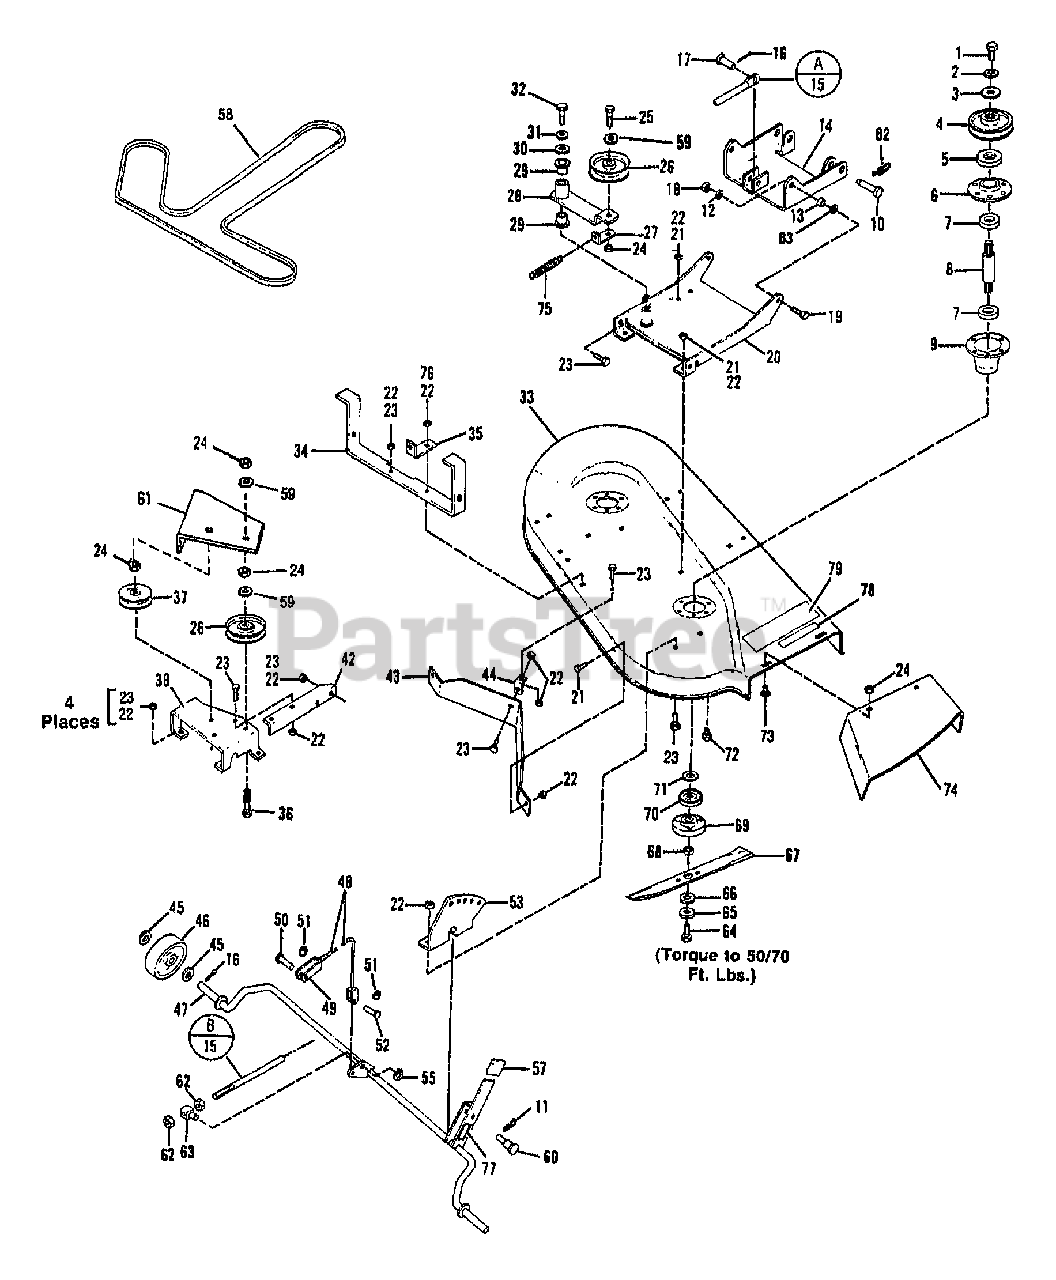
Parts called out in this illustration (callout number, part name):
1	SCR-HH 7/16-14X2.75 G5ZP
1	SCR-HH 7/16-14X3.0 G5 ZP
2	WASHER-LK .438 ZP
3	WASHER-1.37X.453X.179 ZP
4	ASSM-DRIVE SHEAVE
5	BEARING-UPPER SHIELD
6	HOUSING-ARBOR TOP
7	BEARING-BALL
8	SHAFT-ARBOR
9	HOUSING-ARBOR BOTTOM
10	PIN-CLEVIS .62X2.50 ZP
11	PIN-HITCH .125X2.56 ZP
12	WASHER-1/2 FLAT
13	SPACER-TUBULAR
14	ASSM-MOWER SUPT
15	ROD-ADJUSTOR
16	PIN-COTTER .120X1.25 ZP
17	PIN-CLEVIS .5X1.75 ZP
18	NUT-TOP LOCK 1/2-13 ZP
19	SCR-HH 1/2-13X1.25 G5 ZP
20	PLATE-MOWER SUPPORT
21	SCR-CARR 5/16-18X.75
22	NUT-TOP/LK 5/16-18 ZP
23	SCR-HHC 5/16-18X.75 GR 5 ZP
24	NUT-LOCK 3/8-16
25	SCR-HH 3/8-16X2.0 G5 ZP
27	GUIDE-BELT
28	ASSM-IDLER ARM
29	BEARING-FLANGE
30	WASHER-FLAT
31	WASHER-LK .375 @ DEPL
32	SCR-HH 3/8-16X.75 G5 ZP
33	ASSM-MOWER BASE
35	SPRING-ANCHOR
36	SCR-HH 3/8-16X2.25 G5 ZP
37	PULLEY-IDLER
39	SUPT-IDLER/AXLE
42	BRKT-SUPPORT
44	BRACKET-MOWER
45	WASHER-1.38 X.765X .06 ZP
46	GAUGE-WHEEL
47	ASSM-SUPT WHEEL SHAFT
48	ASSM-CABLE(MOWER DECK)
49	YOKE
50	PIN-CLEVIS .5X1.437 ZP
51	RING-CIRCLE COTTER
52	PIN-CLEVIS .375 X .937 ZP
53	QUADRANT
55	RING-RETAINING EXT .694 ID
57	GRIP-HANDLE
59	WASHER-FLAT 3/8 SAE
62	NUT-HEX
63	BLOCK-PIVOT
64	SCR-HH 1/2-14X1.00
65	WASHER-LK CONICAL .49 ID
66	WASHER-SPLINED
67	BLADE-MOWER
68	COLLAR-ARBOR
69	ADAPTER-BLADE
70	SHIELD-GRASS
71	WASHER-SHIM
72	SCR-HFLK 5/16-18X.75
73	SCR-CARR 3/8-16X.75 G5 ZP
74	DEFLECTOR-MOWER
75	SPRING-EXTENSION
76	SCR-HH 5/16-18X1.0 G5 ZP
77	DECAL-HEIGHT ADJUSTOR
78	DECAL-CUTTING LINE
79	DECAL-DANGER
82	RING-COTTER
83	WASHER
